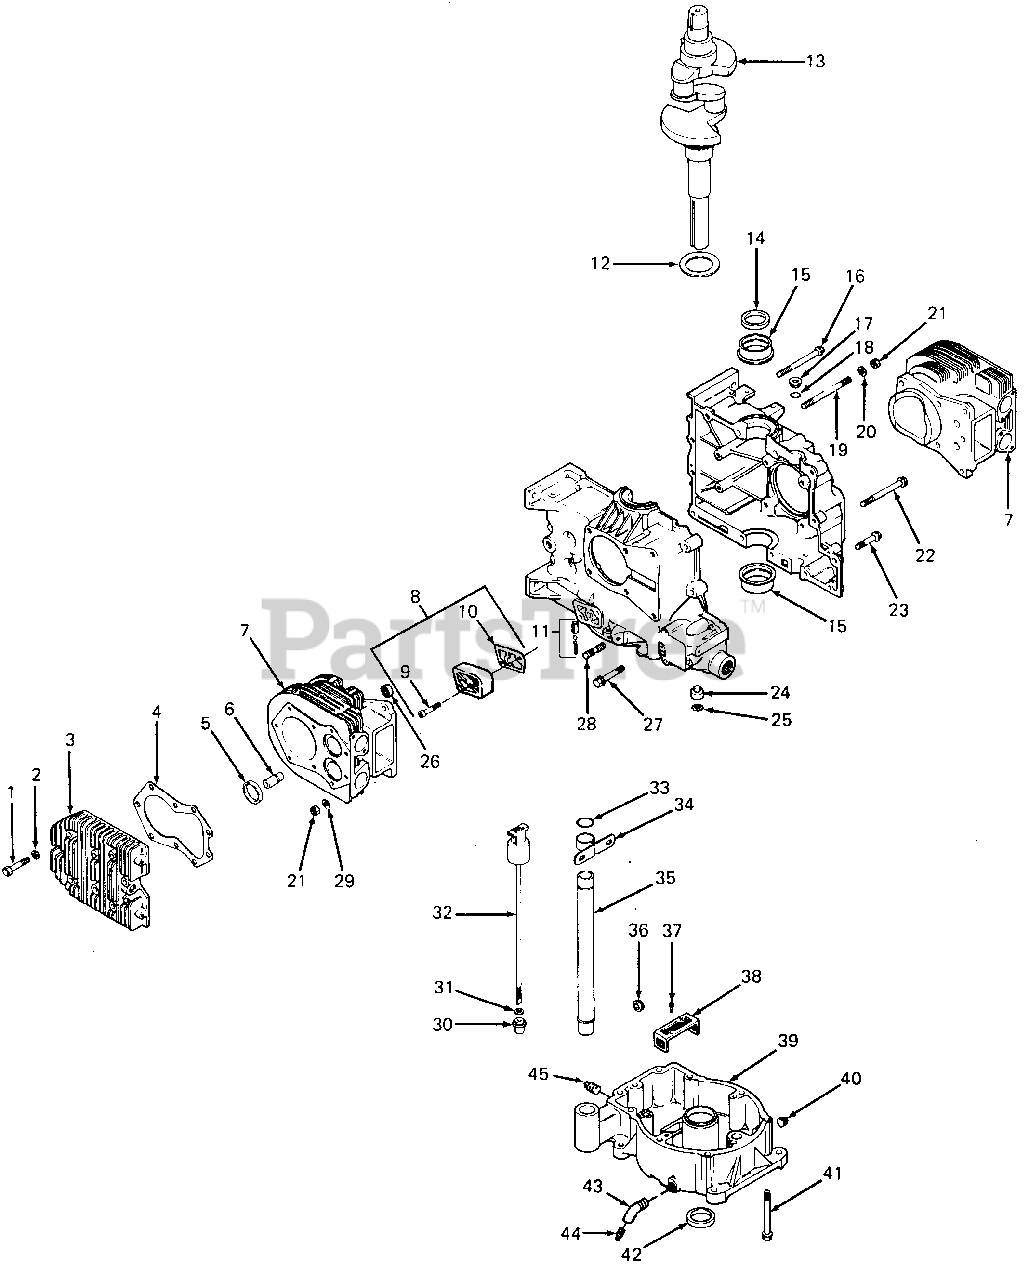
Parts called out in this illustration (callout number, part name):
1	Screw, Hex Hd, 5/16-18 X 1-1/2
2	Washer, Plain, 5/16
3	Head, Cylinder
4	Gasket, Cylinder Head
5	Insert, Valve Seat
6	Valve, Guide
7	Barrel, Cylinder Assy
8	Oil Filter Kit, Non-Filter Cover
9	Screw, Hex Socket Hd, 5/16-18 X 1-1/4
10	Gasket, Oil Filter
11	Oil Relief Kit
12	Washer, Thrust, .119/.122
13	Crankshaft, 3-5/32 X 1 in. Tapped PTO
14	Seal, Front Oil
15	Bearing, Sleeve, Std
16	Screw, Hex Flange, 5/16-18 X 3-1/2
17	Plug, 3/4 in. O.D.
19	Stud, 5/16-18 X 4-1/8
20	Washer, Plain
21	Nut, Hex, 5/16-18
22	Screw, Hex Flange, 3/8-16 X 3-5/8
23	Screw, Hex Flange, 5/16-18 X 1-1/2
24	Shaft, Governor
25	Ring, Retaining
26	Bushing, Locating
27	Screw, Hex Flange, 5/16-18 X 2
28	Stud, Step, 5/16-18 X 3/4, 3/8-16 X 5/8, 2 in. Lg
29	Washer, Flat, 5/16
30	Seal, Rubber
31	Washer, Plain, 5/16
32	Dipstick, 13-1/2 in. Blade
34	Bracket, Oil Tube Support
35	Tube, Oil Fill, 11-7/8
36	Plug, Hex Ctsk, 3/4 NPTF
37	Screw, Hex Wash Hd, 10-32 X 7/16
38	Filter, Oil Pickup
39	Pan, Oil
40	Plug, Sq Solid Hd, 3/8 NPTF
41	Screw, Hex Wash Hd, 5/16-18 X 3-1/4
42	Seal, Rear Oil
43	Pipe, Oil Drain
44	Plug, Pipe, H-Hd Auto, 1/4-18 ZNP
45	Plug, Hex Ctsk, 1/4 NPTF
